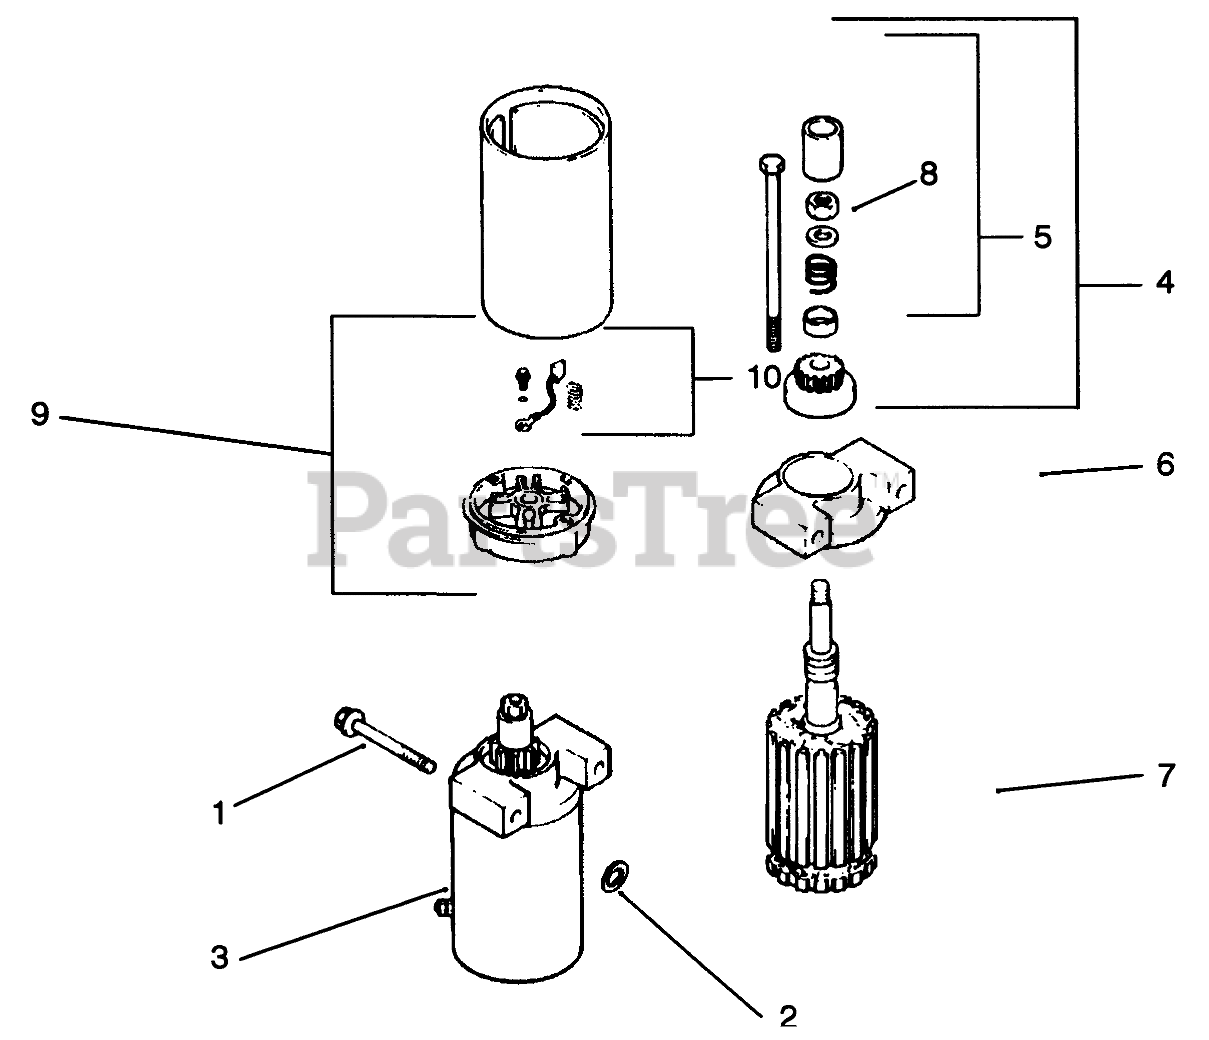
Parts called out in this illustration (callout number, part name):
2	Washer
3	Starter (Incl. Ref.#4-10)
4	Kit-Drive (Incl. Ref.#5)
5	Kit
6	Cap-Drive End
7	Armature
8	Screw-Flange
9	Cap-Commutator End
10	Kit-Brush
